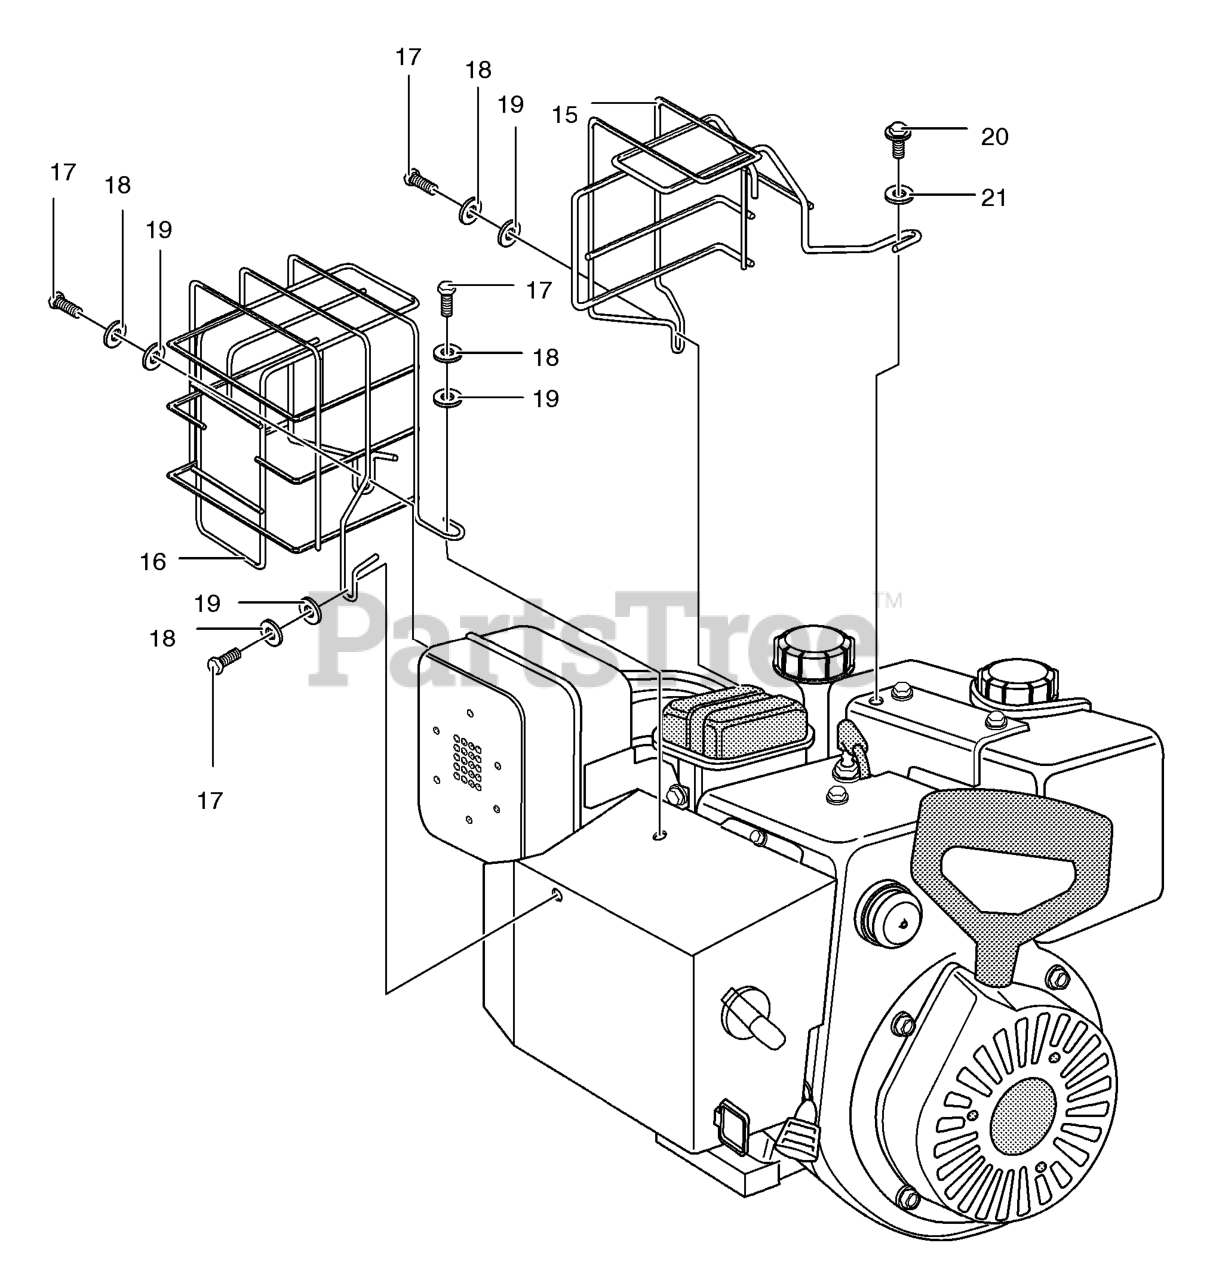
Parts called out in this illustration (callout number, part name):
15	GUARD, RIGHT MUFFLER
16	GUARD, LEFT MUFFLER
18	WASHER
19	WASHER
20	SCREW
